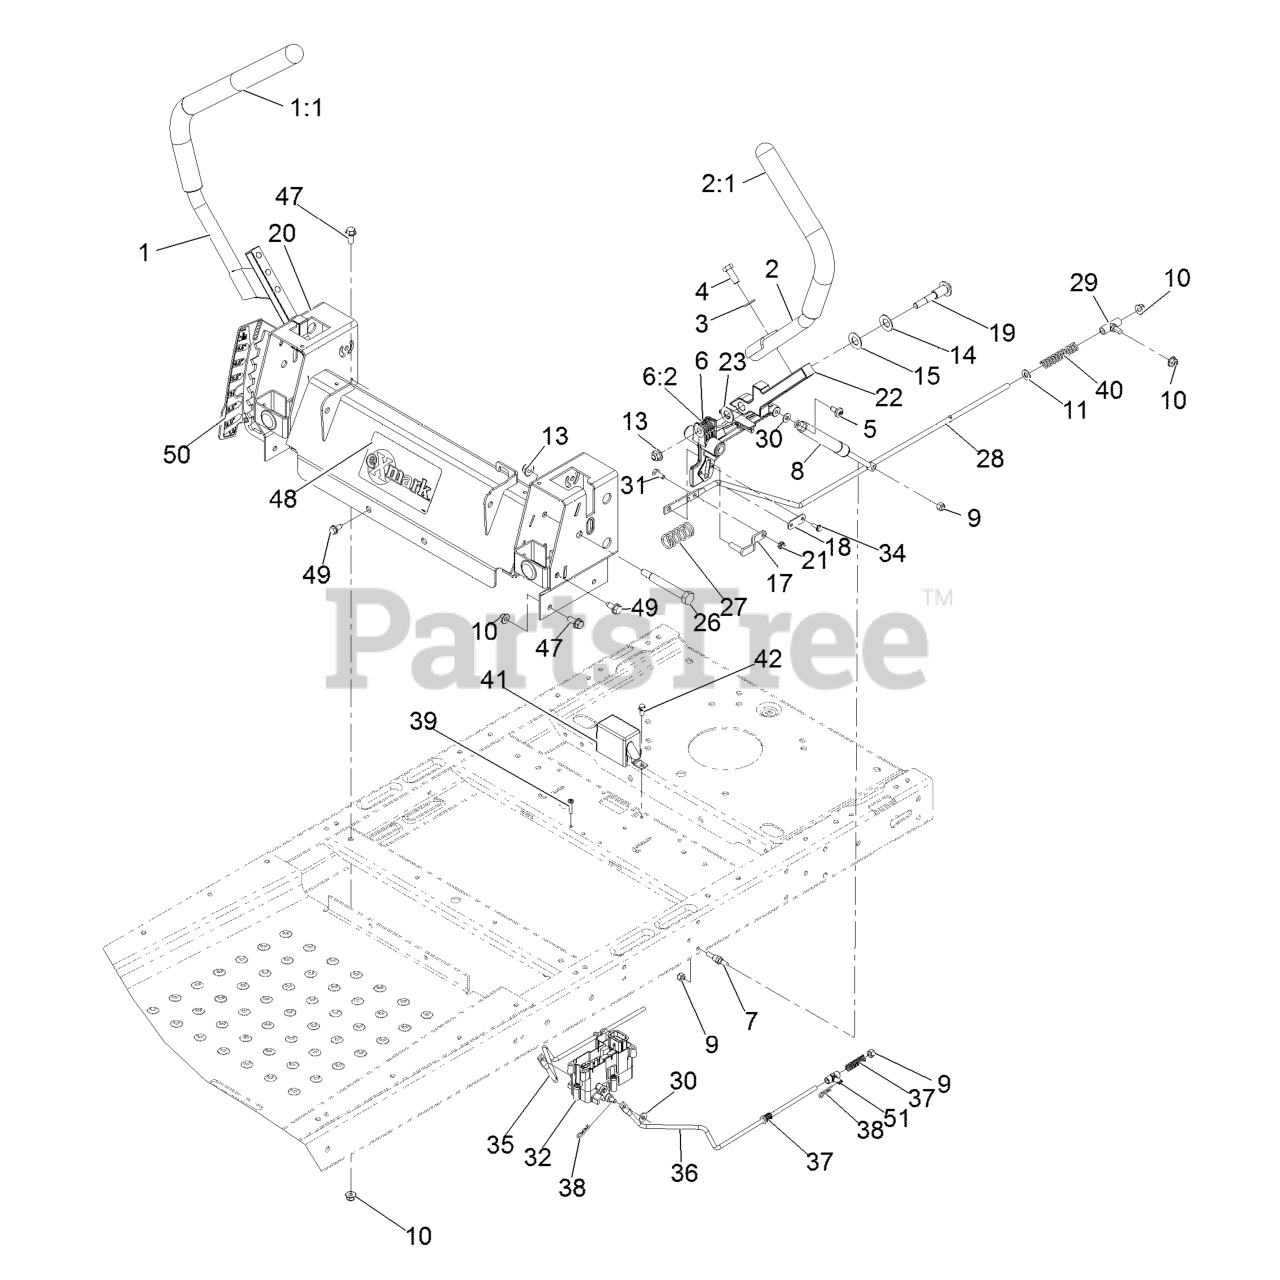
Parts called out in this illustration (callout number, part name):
1	HANDLE-CONTROL, RH
2	HANDLE-CONTROL, LH
3	WASHER-FLAT
4	SCREW-HH
5	SCREW-SHOULDER
6	ACTUATOR ARM ASM
6:2	BUSHING-FLANGE
7	STUD-DAMPER
9	NUT-LOCK, NI
10	NUT-HF, NI
11	WASHER-PLAIN
13	NUT-HF, NI
14	WASHER-BELLEVILLE
18	PLATE-STOP, HYDRO
19	BOLT-PIVOT
20	CONTROL BOX ASM
21	NUT-LOCK, NI
23	WASHER-NYLON
26	BOLT-PIVOT
27	SPRING-RETURN
28	ROD-HYDRO
29	MOUNT-ROD, HYDRO
31	SCREW-HH
34	SCREW-TAPTITE
35	ROD-BRAKE, RH
36	ROD-BRAKE, LH
37	SPRING-COMPRESSION
39	SCREW-PPH
40	SPRING-RETURN, NEUTRAL
41	COVER-BRAKE
42	SCREW-HWH
47	SCREW-HHF
49	Screw-HWH 5/16-18 X 3/4 Tf
50	DECAL-HOC
51	MOUNT-PIVOT
